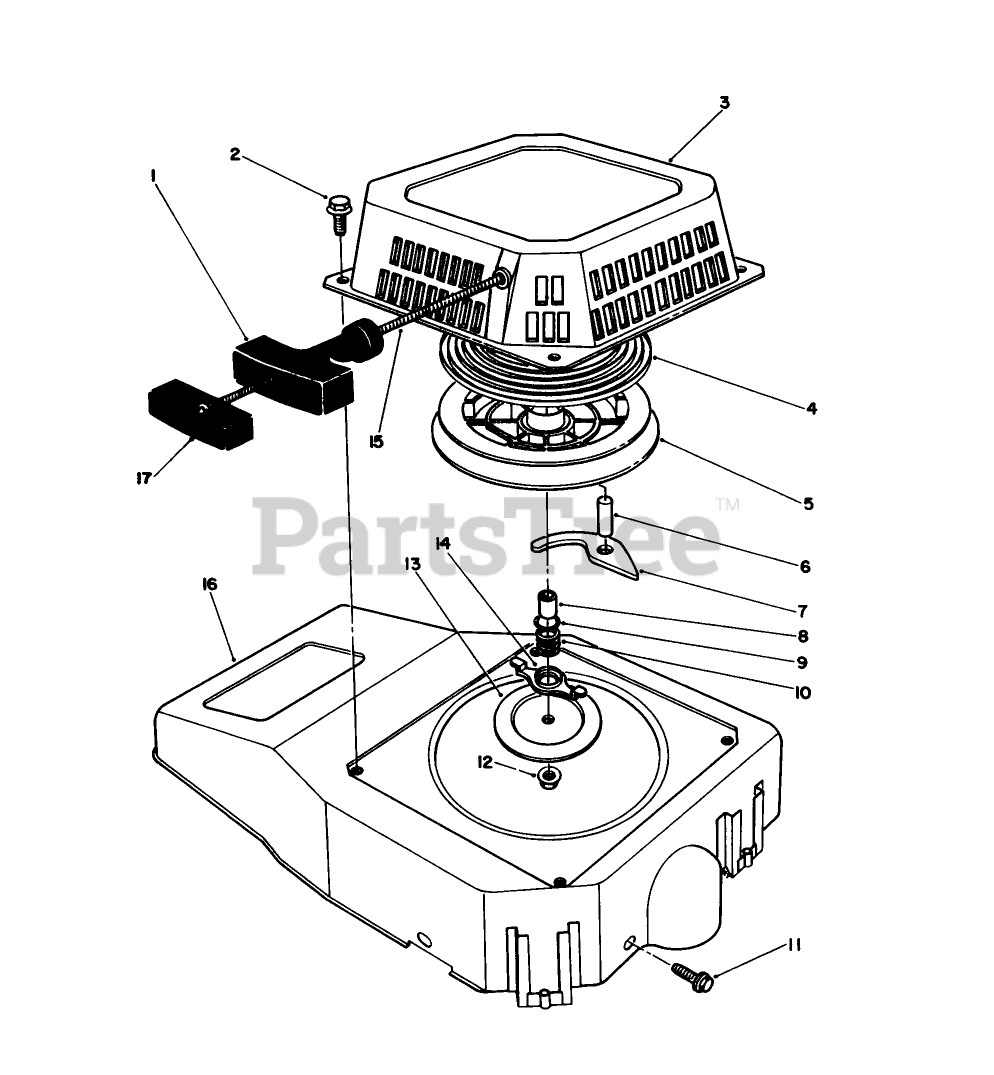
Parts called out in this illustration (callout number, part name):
1	HANDLE
2	SCREW-HHF
4	SPRING
9	WASHER
16	SHROUD
